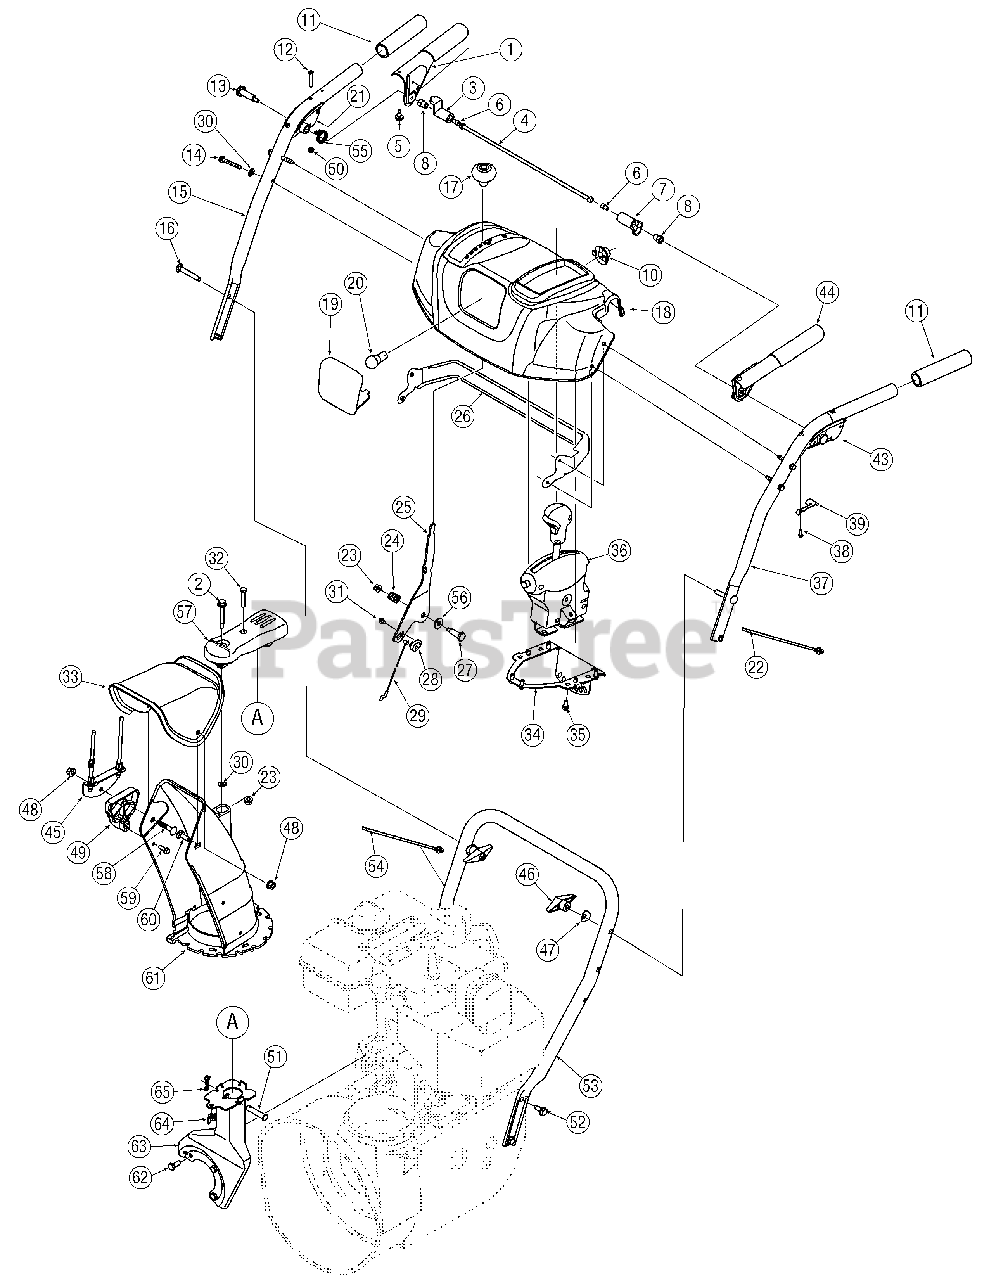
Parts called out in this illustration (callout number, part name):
1	Handle Engagement Assembly RH
2	Flange Shoulder Screw
3	Lock Plate
4	Pivot Rod
5	Rubber Bumper
6	Screw, 1/4-20 x.375
7	Clutch Lock Cam
8	Shoulder Nut, 1/4-20
10	Light Socket
11	Handle Grip
12	Screw, #10-24 x 0.375
13	Shoulder Screw, 1/4-20 x 1.345
14	Screw, 1/4-20 x 1.750
16	Carriage Screw, 5/16-18 x 2.25
17	Shift Knob
18	Handle Panel, K/L-Style, Black
18	Handle Panel, K/L-Style, Gray
20	Lamp
21	Handle Clutch Lock - RH
22	Cable Tie
23	Flange Lock Nut, 1/4-20
24	Compression Spring
28	Cable Barrel Holder
29	Speed Selector Cable
30	Flat Washer, .25 x .630 x .0515
31	Screw, #10-16 x .500
32	Hex Screw, 1/4-20 x 1.50
33	Upper Chute
35	Hi-Lo Screw, 1/4-15 x 0.5
36	4 Way Chute Control Assembly Service Kit
38	Screw, #8-16 x 0.50
39	Clutch Lock Spring
40	Steering Control
41	Pin, 3/16
42	E Ring
43	Handle Clutch Lock - LH
44	Handle Engagement Assembly LH
46	Handle Knob Assembly
47	Saddle Washer
48	Flange Lock Nut, 5/16-18
49	Chute Tilt Cable Guide
50	Hex Lock Nut, #10-24
51	Clevis Pin
52	AB Screw, 5/16-18 x 0.75
54	Cable Tie
55	Torsion Spring
56	Flat Washer
57	Joystick Pulley Cover
58	Carriage Bolt, 5/16-18 x 1.50
59	Hi-Lo Screw, 1/4-15 x .75
60	Carriage Bolt, 5/16-18 x 1.0
61	Lower Chute
62	Hex Screw, 5/16-24 x .750
63	Support Bracket
64	Wing Nut, 1/4-20
65	Bow Tie Cotter Pin
